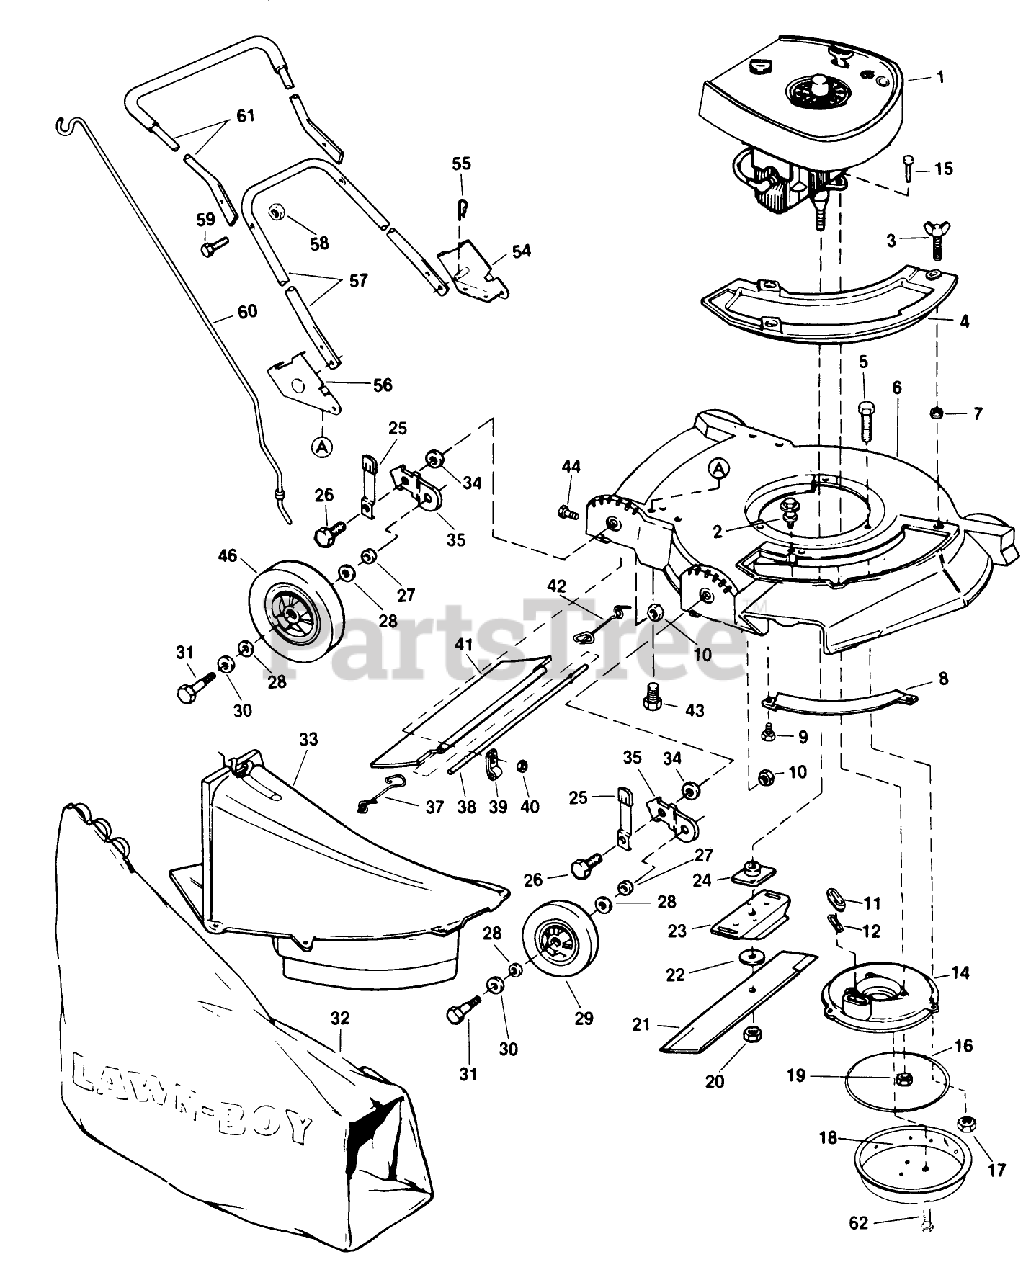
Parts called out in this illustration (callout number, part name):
3	WING SCREW LAWRE
5	SCREW V
8	TOE BAR 19"
8	BAR-TOE
10	LOCKNUT
12	GASKET S
17	NUT-LOCK F
19	NUT-LOCK F
20	NUT-BLADE
22	WASHER
24	PLATE AND COLLAR ASM
27	WASHER WROUGHT
29	WHEEL & TIRE KIT
31	BOLT WHEEL
32	89802 LB WHOLE GOODS
37	SPRING;TRAILING SHIELD RH
38	ROD T/SHIELD ADV WIRE
38	ROD 21" ADVANCE
39	CLAMP ROD KMC
40	LOCKNUT E
42	SPRIG T/SHLD ASOC
55	HAIR PIN
58	LOCKNUT E
60	ROD GRASSBAG
